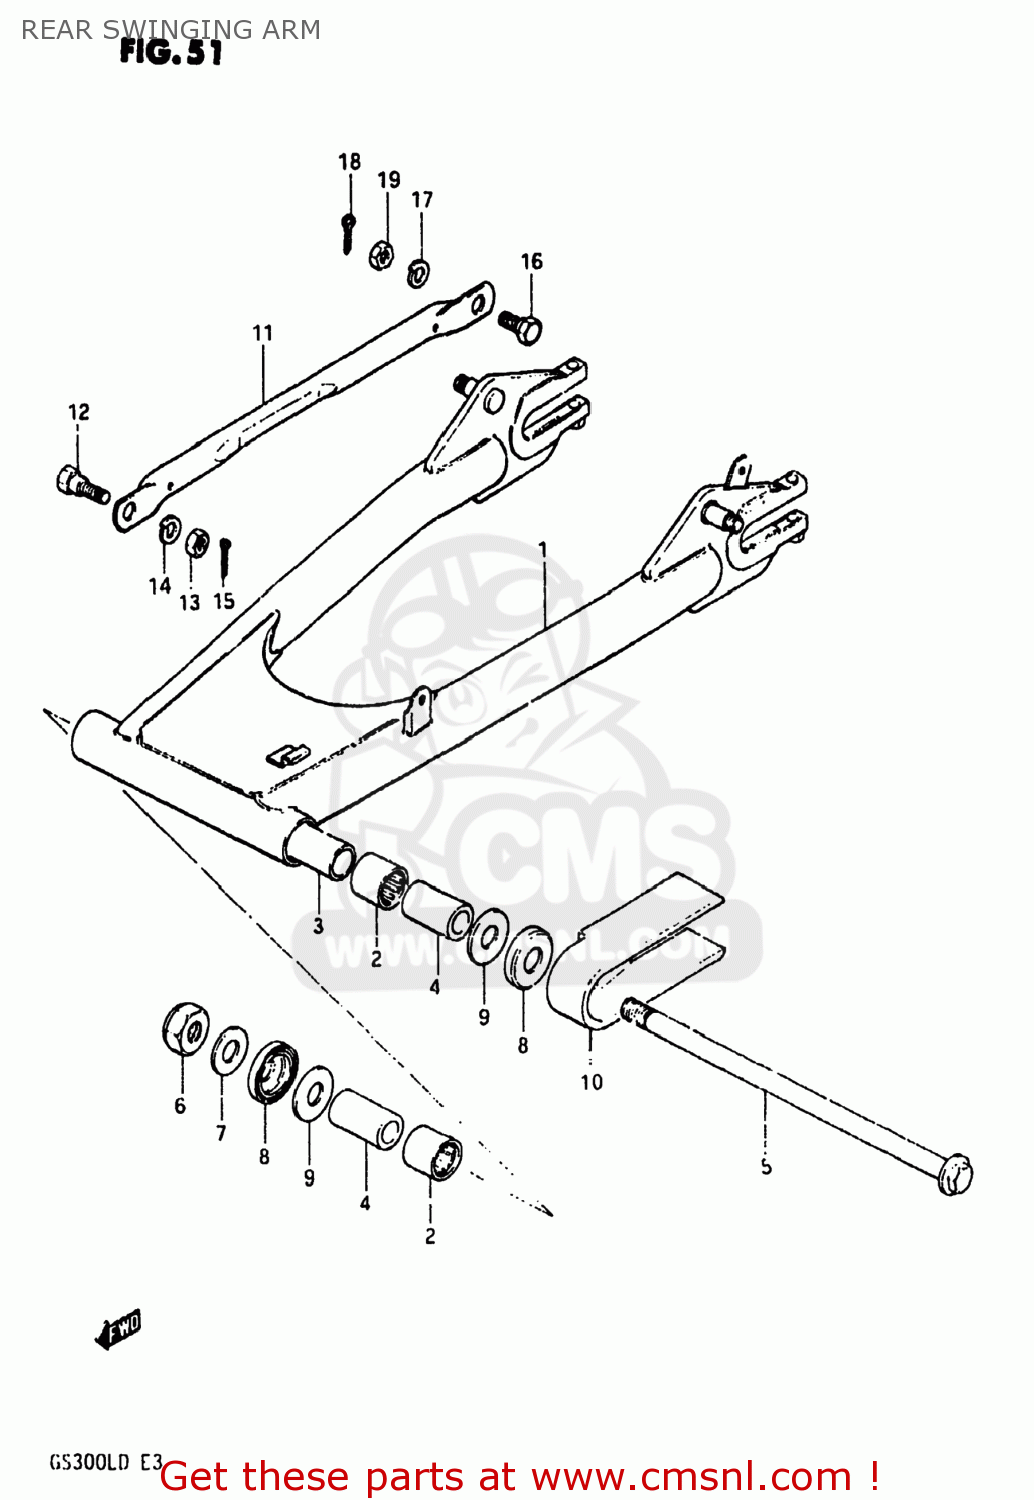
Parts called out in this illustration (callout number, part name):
1	ARM,REAR SWING
2	BEARING(22X29X30)
3	SPACER,SWINGINGARM CTR
4	SPACER,RR SWGARM PIVOT
5	SHAFT,REAR SWING ARM
6	NUT 14MM
7	WASHER
8	CVR,RR SWGARM DUST SEAL(OD:40)
9	WASHER(14.2X34X1)
10	BUFFER,CHAIN TOUCH DEFLECTOR
11	LINK,REAR TORQUE
12	BOLT(10X24.5)
13	NUT
14	LOCK WASHER
15	PIN 20X20
16	BOLT(10X31)
17	LOCK WASHER
18	PIN 20X20
19	NUT
